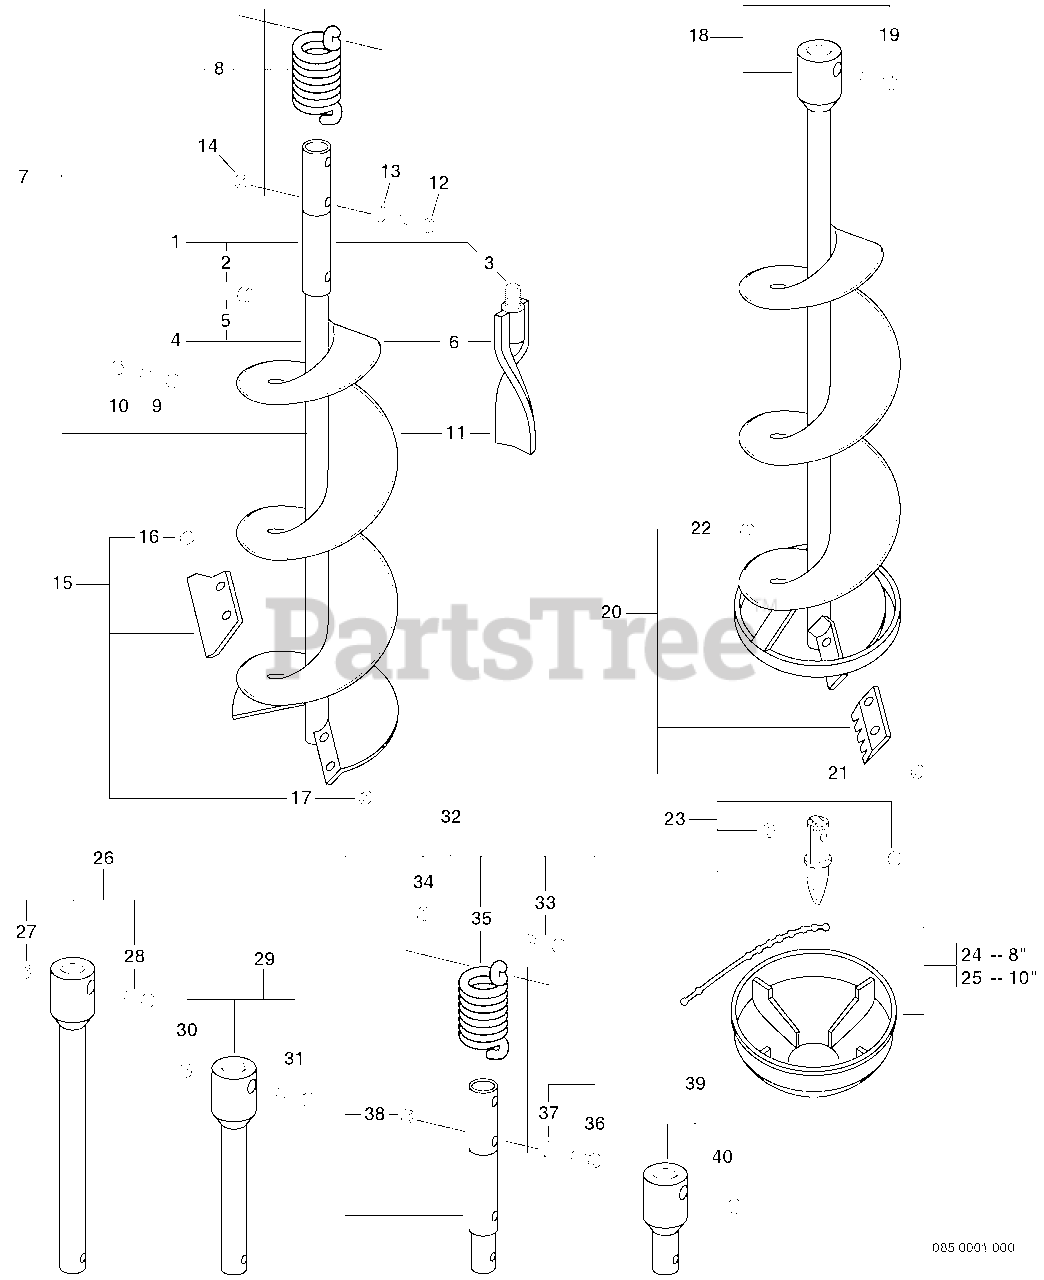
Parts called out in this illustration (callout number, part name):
1	EARTH AUGER W/POINT - 2"
1	EARTH AUGER W/POINT - 3"
2	SCREW - 3/8 X 16 X 1-1/4"
3	EARTH AUGER POINT
4	EARTH AUGER W/POINT - 4"
5	SCREW - 3/8 X 16 X 1-1/4"
6	EARTH AUGER POINT
7	EARTH AUGER ASSY - 6" (15cm)
7	EARTH AUGER ASSY - 8" (20cm)
7	EARTH AUGER ASSY - 10" (25cm)
9	BOLT - 3/8-16 X 1-1/2"
10	LOCKNUT - 3/8-16
11	EARTH AUGER POINT
12	BOLT - 5/16-18 X 2"
13	WASHER - 5/16"
14	LOCKNUT - 5/16-18
15	EARTH AUGER BLADE KIT - 4"
15	EARTH AUGER BLADE KIT - 6"
15	EARTH AUGER BLADE KIT - 8"
15	EARTH AUGER BLADE KIT - 10"
16	BOLT - 1/4-28 X 5/8"
17	NUT - 1/4-28
18	ICE AUGER DUAL BLADE - 8"
18	ICE AUGER DUAL BLADE - 10"
19	SCREW - 3/8 X 16 X 1-1/4"
20	ICE AUGER DUAL BLADE KIT - 8"
20	ICE AUGER DUAL BLADE KIT - 10"
21	SCREW - 5X16
22	LOCKNUT - 5
23	ICE AUGER POINT KIT
24	ICE AUGER COVER - 8"
25	ICE AUGER COVER - 10"
26	EXTENSION SHAFT - 18" (7/8" DIA)
27	LOCKNUT - 3/8-16
28	BOLT - 3/8-16 X 1-1/2"
29	EXTENSION SHAFT - 12" (7/8" DIA)
30	LOCKNUT - 3/8-16
31	BOLT - 3/8-16 X 1-1/2"
32	ADAPTOR W/SPRING - 7/8" TO 1"
33	BOLT - 3/8-16 X 1-1/2"
34	LOCKNUT - 3/8-16
36	BOLT - 5/16-18 X 2"
37	WASHER - 5/16"
38	LOCKNUT - 5/16-18
39	ADAPTOR - 7/8" TO 1"
40	SCREW - 3/8 X 16 X 1-1/4"
